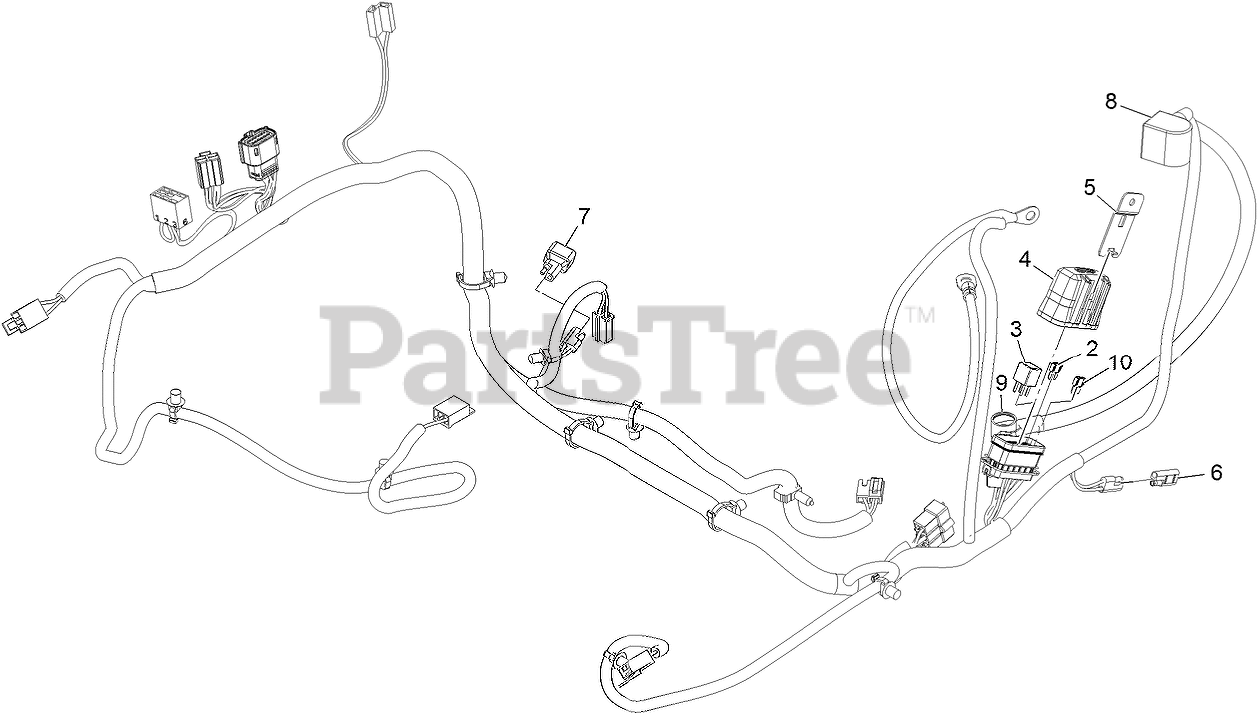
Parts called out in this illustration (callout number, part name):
2	FUSE-MINI BLADE, 20 AMP
3	RELAY-MICRO
4	COVER-BLOCK, FUSE
5	CLIP-MOUNTING
6	CAP-PLUG
8	INSULATOR-BATTERY
9	INSULATOR-SOLENOID
10	FUSE-MINI BLADE, 15 AMP
